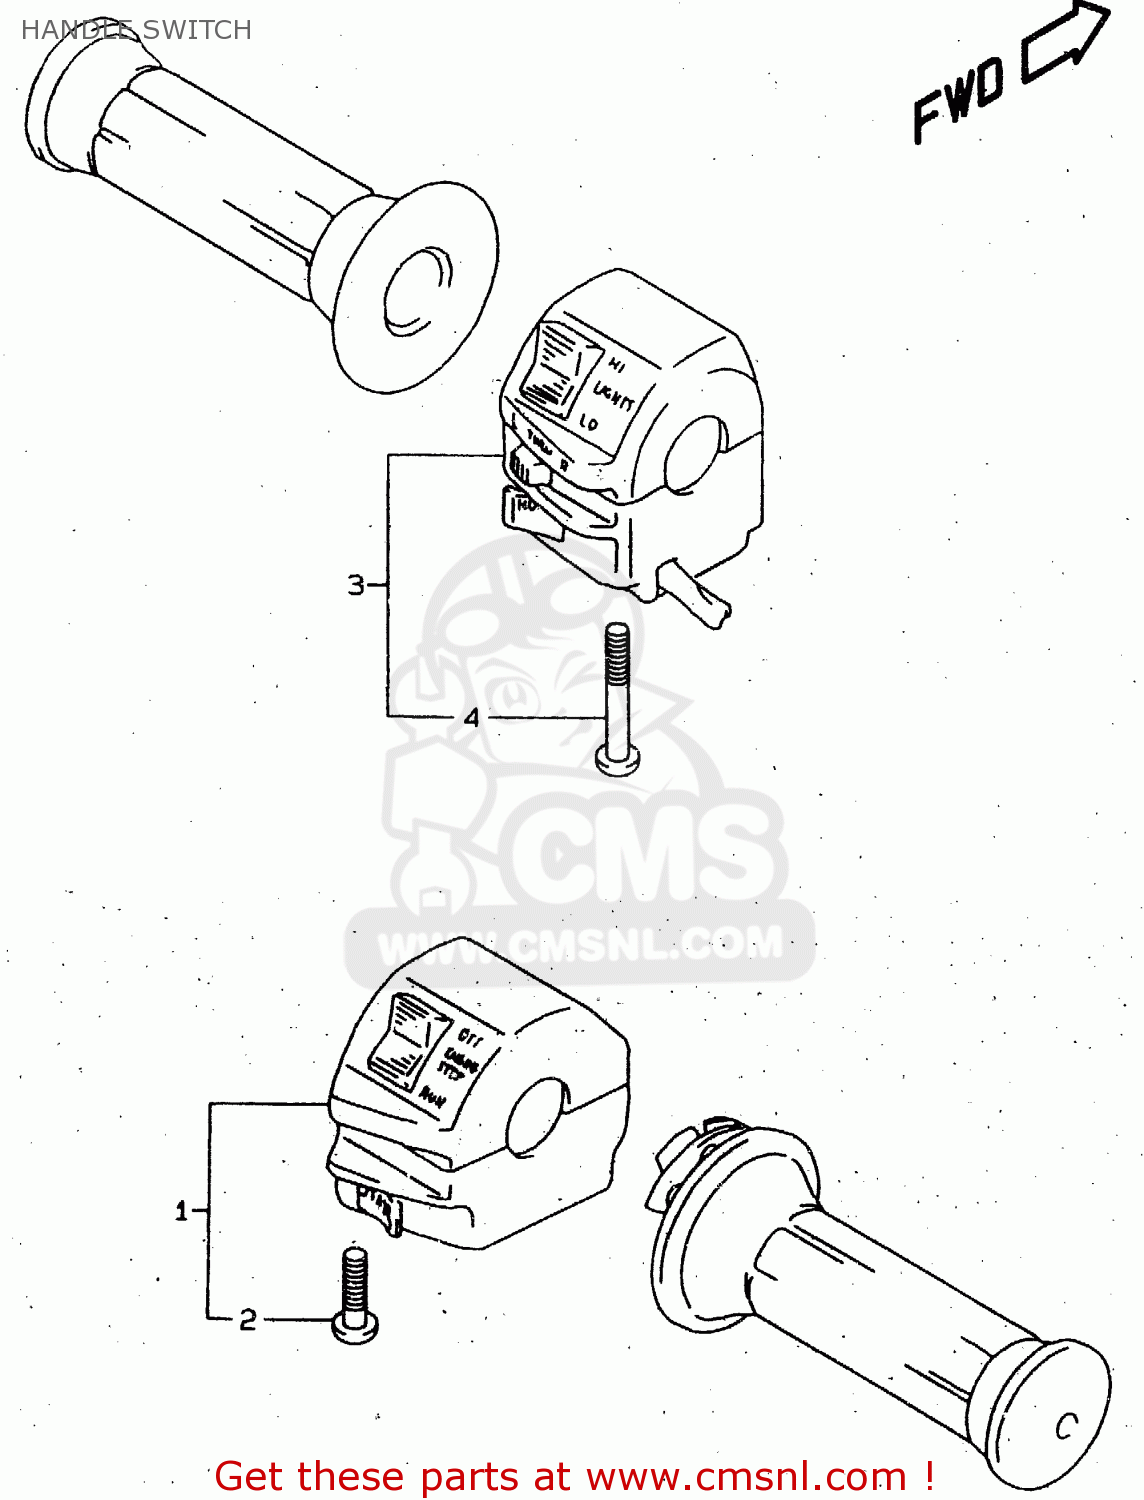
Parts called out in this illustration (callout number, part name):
1	SWITCH ASSY,HANDLE,R
2	SCREW
3	SWITCH ASSEMBLY,HANDLE,LEFT
4	SCREW
